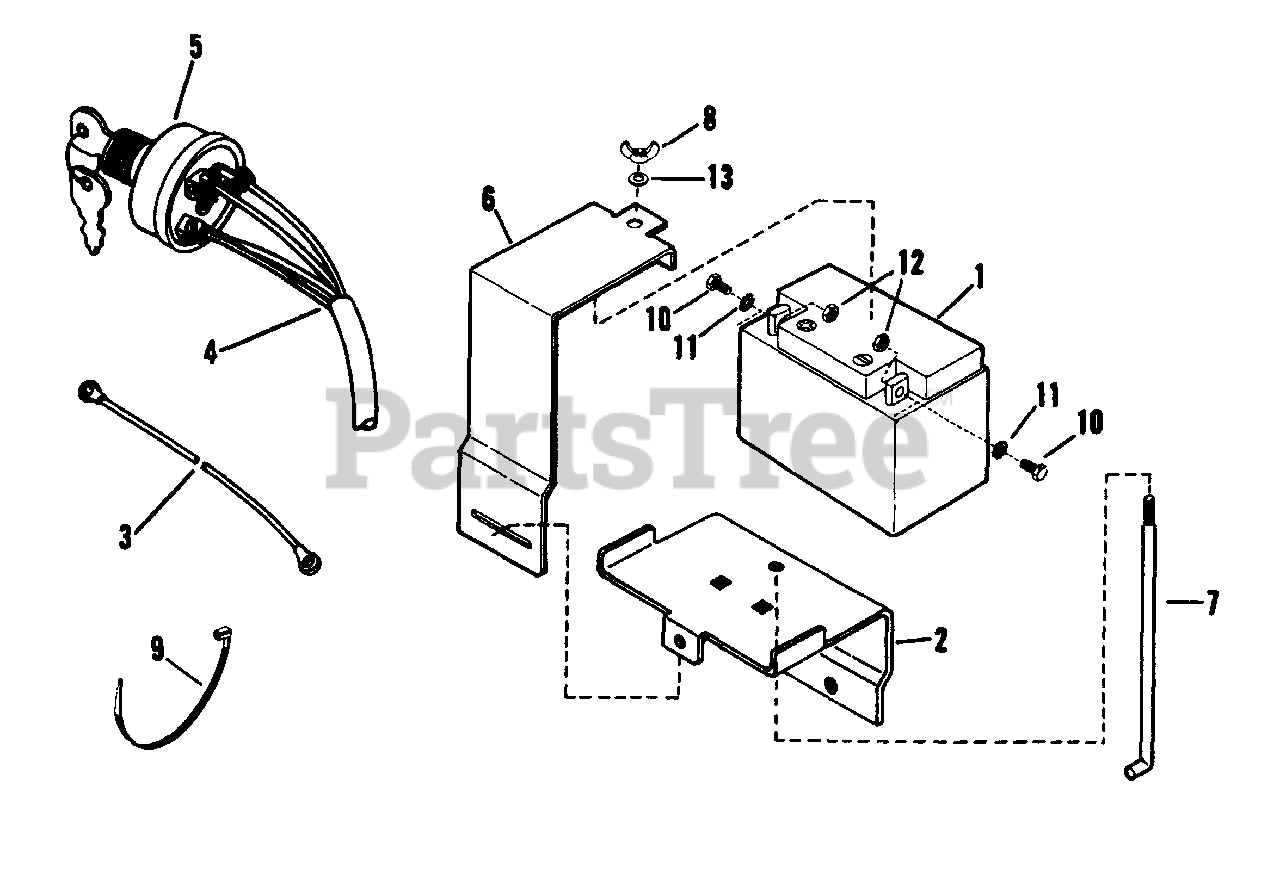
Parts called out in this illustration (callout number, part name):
1	BATTERY, 12 Volt Sealed Lead Acid Zm-12
2	BRACKET, Battery Mounted
3	WIRE, Negative
4	HARNESS, Wiring
5	SWITCH, Electric Start
6	RETAINER, Battery
7	ROD, Battery Hold-Down
8	WING-NUT, 1/4-20
9	CABLE TIE
10	SCREW, #10-24 x 1/2" Hex Head Cap
11	WASHER, #10 External Tooth Lock
12	NUT, #10-24 Hex Twin-Lock
13	WASHER, 1/4" SAE Flat
